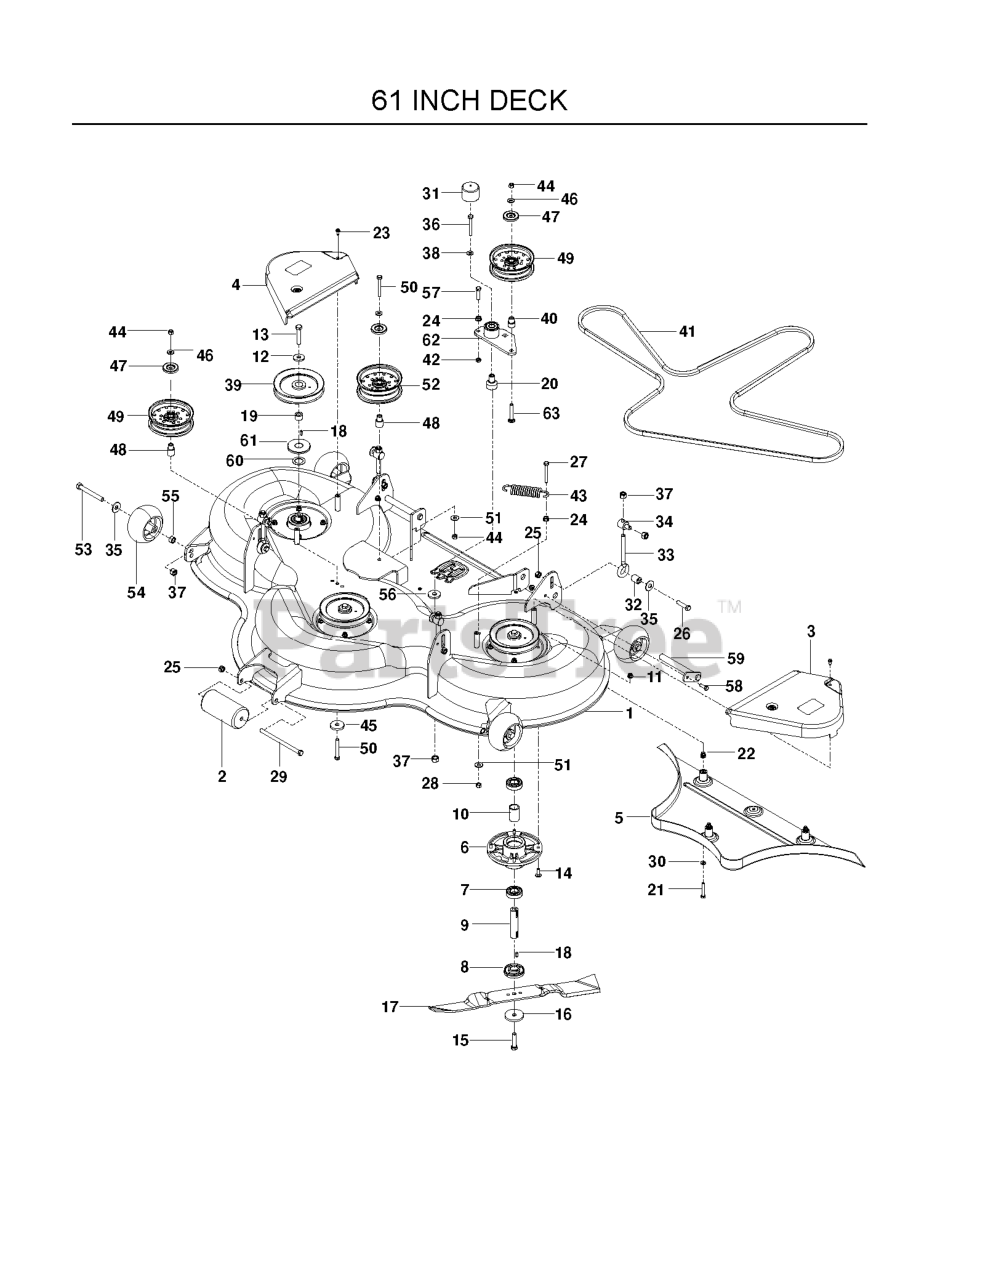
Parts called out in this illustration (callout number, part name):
1	DECK W/DECALS, 61" HUS
2	ROLLER
3	BELT SHIELD LT
4	BELT SHIELD RT
5	PLUG ASSEMBLY
6	BEARING HOUSING
7	BALL BEARING
8	BUSHING, BLADE
11	5/16-18 NYLOC FLANGE NUT
12	WASHER-.533IDX1.37OD
13	HCS M12 X 1.75 X 60 GR5 ZD
14	RHSNB 5/16C X 1
15	HCS M12 X 1.75 X 50 GR8.8 ZD
19	KEY RETAINER
20	PIVOT, BEARING
21	HCS M8 X 1.25 X 50 GR8.8 ZD
22	BLIND RIVET NUT
23	SCREW 1/4 X 5/8
24	NUT 3/8C WHIZ
25	NUT 7/16C CENTERLOCK
26	HCS 7/16 - 14 X 1 3/4
27	HCS 3/8C X 2
28	NUT HEX 3/8-16 NYLON, THIN
29	HCS 7/16-14 X 7 GR5 ZD
30	FLAT WASHER 5/16 SAE
31	CAP, VINYL
34	SWIVEL, DECK HEIGHT ADJ
35	WASH USS FLAT 1/2
36	SCREW, 1/2C X 3 HEX CAP
37	NUT 1/2-13 HEX NYLOC ZD
38	CONTACT BELLSPR 1/2
39	PULLEY, 61
40	BUSHING, IDLER
41	DECK BELT, 61 CMB
42	NUT 3/8-16 HEX JAM
44	NUT 3/8-16 NYLOC
45	SPINDLE WASHER
46	WASHER, 3/8 THICK
47	DUST SHIELD
48	IDLER BUSHING
49	IDLER PULLEY
50	SCREW 3/8C X 2 3/4 HEX CAP
51	WASHER 3/8 FLAT
52	IDLER PULLEY (TALL)
53	HCS 1/2-13 X 4 GR 5 ZD
54	GAUGE WHEEL
55	HCS 3/8-16 X 1-1/2
56	WASHER, SUPPORT
57	HCS 3/8-16 X 1-1/2
58	HCS 5/16C X 1
59	PIN, STRUT, WELDMENT
60	WASHER-1.06IDX1.63ODX.06
61	BOTTOM DUST CAP
62	ARM-IDLER W/BRG
63	CARRIAGE BOLT 3/8-16 X
